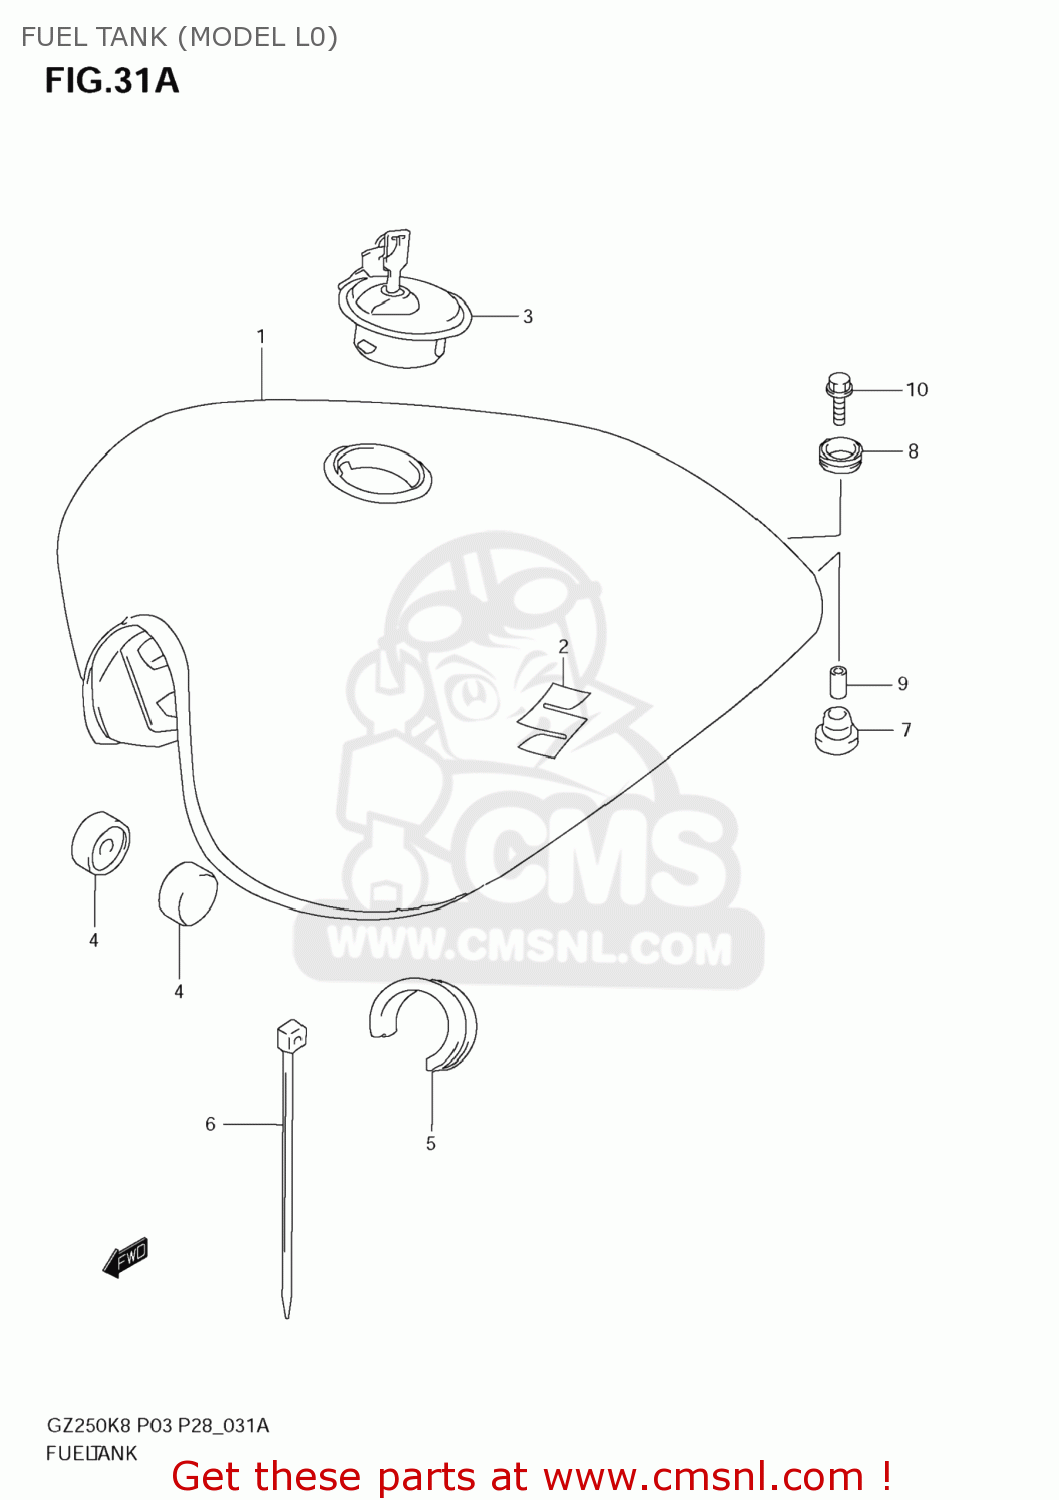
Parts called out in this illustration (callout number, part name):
1	TANK ASSY,FUEL(BLACK)
2	EMBLEM,S
3	CAP SET,FUEL TANK
4	CUSHION
5	CUSHION,FUEL TANK SIDE
6	CLAMP
7	CUSHION
8	CUSHION,FUEL TANK RR
9	SPACER(6.5X9X18)
10	BOLT
